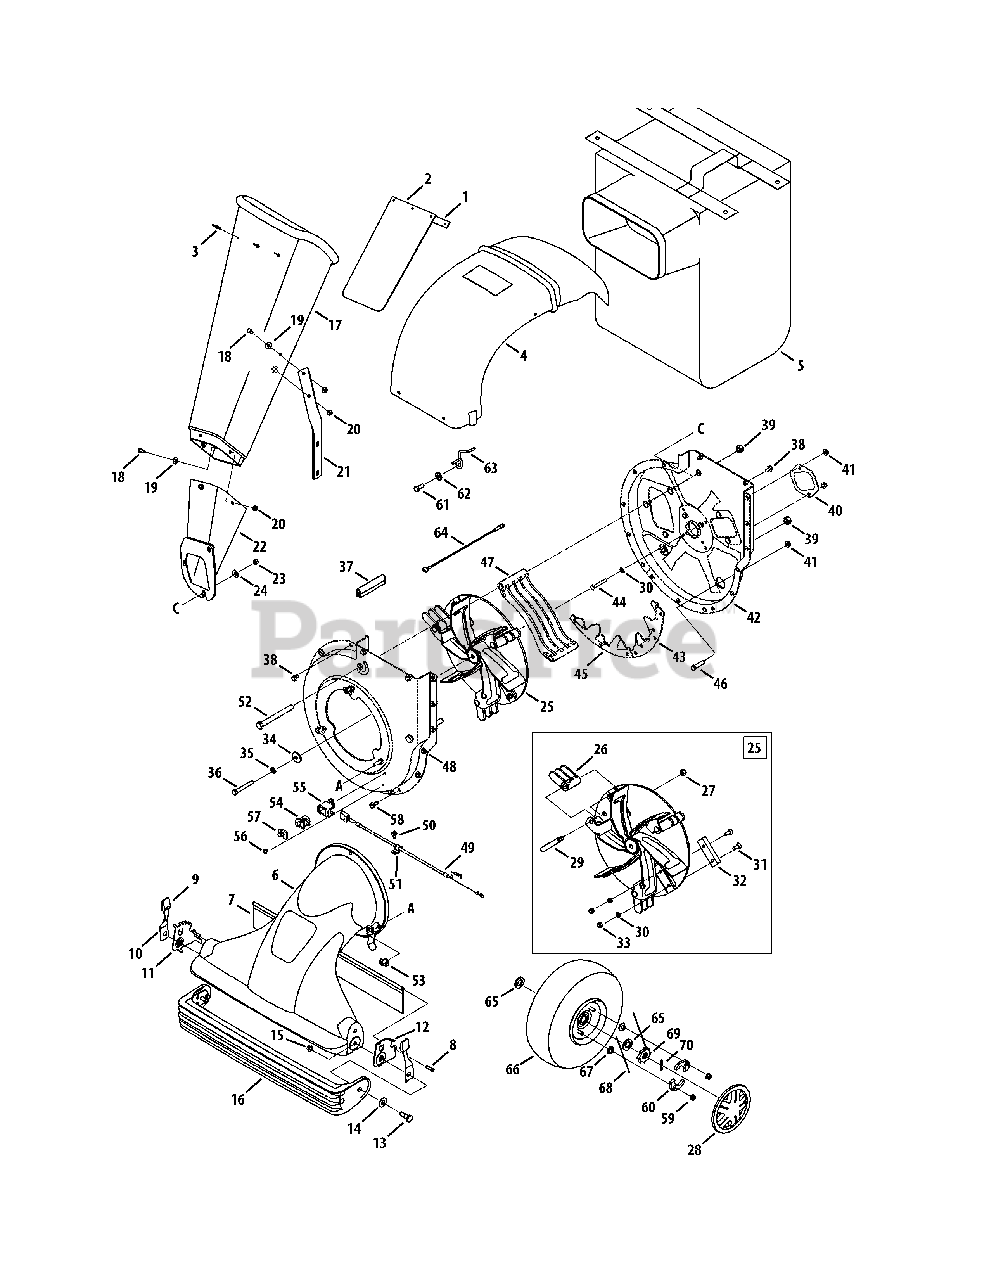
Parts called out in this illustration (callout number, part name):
1	Chute Flap Strip
2	Chute Flap
3	Pop Rivet
4	Discharge Chute
6	Nozzle Assembly
7	Nozzle Flap
9	Height Adjustment Knob
10	Spring Lever
11	Index Bracket RH
12	Index Bracket LH
13	Shoulder Screw
14	Flat Washer, .510 x 1.12 x.060
15	Hex Flange Lock Nut, 3/8-16
16	Door Assembly
17	Chipper Chute
18	Hex Cap Screw, 1/4-20 x.620
19	Flat Washer, .28 ID x.74 OD
20	Hex Lock Nut, 1/4-20
21	Support Bracket
22	Chipper Chute Assembly
23	Hex Nut, 5/16-18
24	Bell Washer, .340ID x.872OD
25	Impeller Assembly: Complete
26	Flail Blade
27	Jam Lock Nut, 3/8-16
29	Shoulder Pin, .5 x 2.625
30	Lock Washer, 5/16
31	Cap Screw 5/16-24 x 1.0
32	Chipper Blade
33	Hex Lock Nut 5/16-24
34	Flat Washer, .406 x 1/1/4
35	Lock Washer, 3/8
36	Hex Cap Screw, 3/8-24 x 2.75
37	Rubber Seal
38	Hex Washer Screw, 5/16-18
39	Hex Lock Nut, 1/2-13
40	Chipper Blade Cover
41	Hex Flange Lock Nut 5/16-18
42	Housing Assembly: Inner Flail
43	Upper Shredder Blade
44	Hex Cap Screw, 5/16-18 x 2
45	Flail Housing Blade
46	Hex Cap Screw, 5/16-18 x.75
47	Discharge Screen
48	Housing Assembly: Outer Flail
49	Wire Harness
50	TT Screw, 1/4-14 x 0.625"
52	Hex Cap Screw, 1/2-13 x 5.0
53	Knob, 5/16-18
55	Safety Switch Mounting Cover
56	Hex Washer Screw
57	Switch Cover
58	LD Screw, 5/16-18 x 0.75"
59	Hex Flanged Lock Nut, 1/4-20
60	Pawl, .345 ID -LH
60	Pawl, .345 ID - RH
61	Hex Cap Screw, 5/16-24 x.75
62	Flat Washer, .344 x.75 x.12
63	Belt Keeper
64	Adapter Harness Assembly
65	Flat Washer, 5/8 ID x 1.0 OD
66	Wheel Complete 10 x 4 x 4
67	Hex Nut, 1/4-20
68	Plastic Spring Ratchet
69	Wheel Ratchet 1.62 OD x.5 serr
70	Cotter Pin
